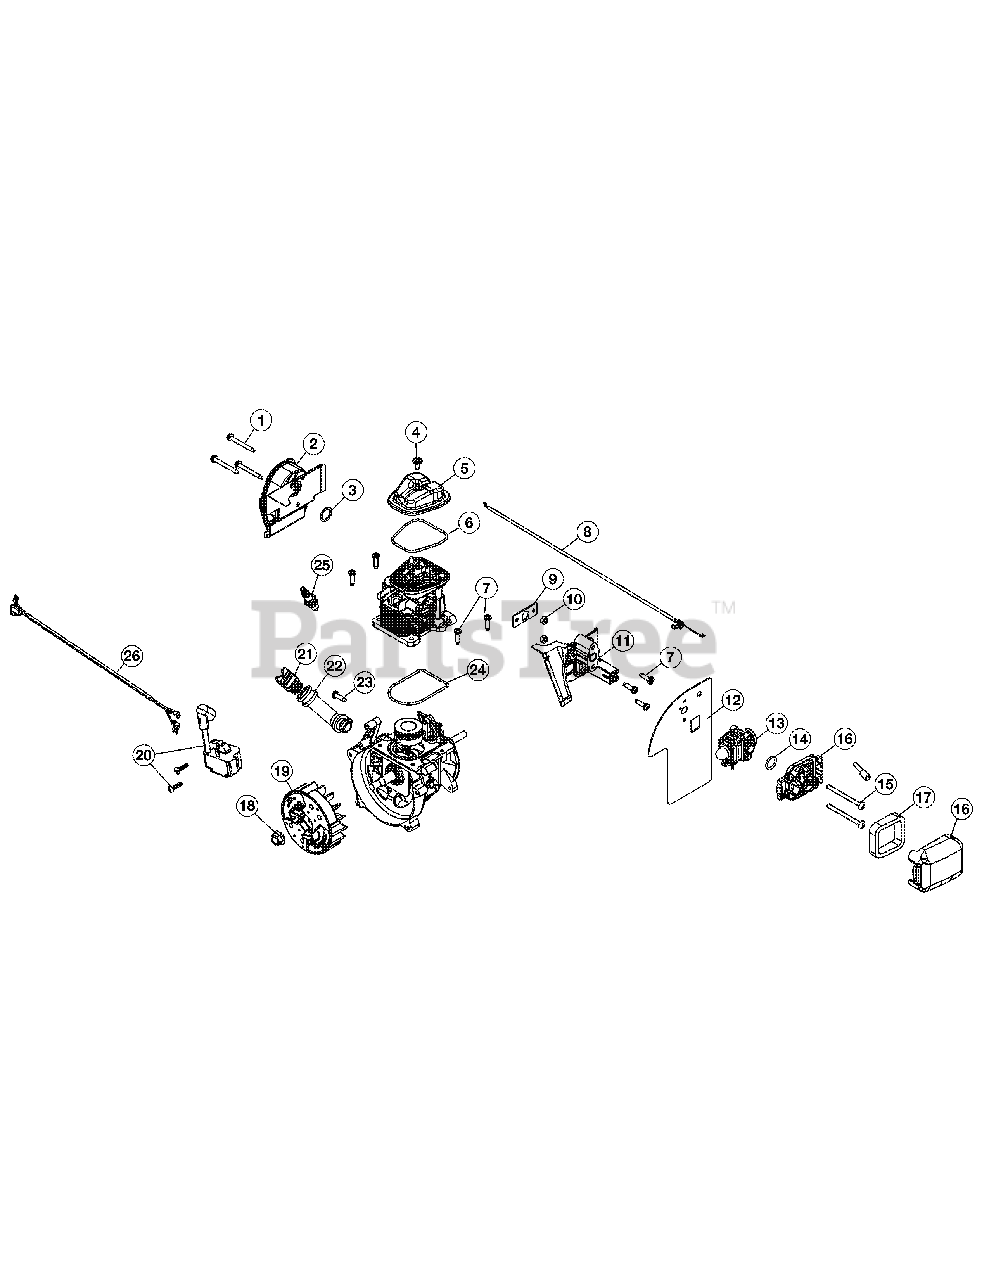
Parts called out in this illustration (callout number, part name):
1	Muffler Screws
2	Muffler Assembly
3	Muffler Gasket
5	Rocker Cover
7	Screw
8	Throttle Cable
9	Insulator Gasket
10	Nut
12	Carburetor Gasket
13	Carburetor
14	Carburetor O-Ring
15	Screw
16	Air Cleaner Assembly
18	Nut
19	Flywheel Assembly
21	Oil Plug
22	Oil Fill Tube
23	Screw
25	Spark Plug
